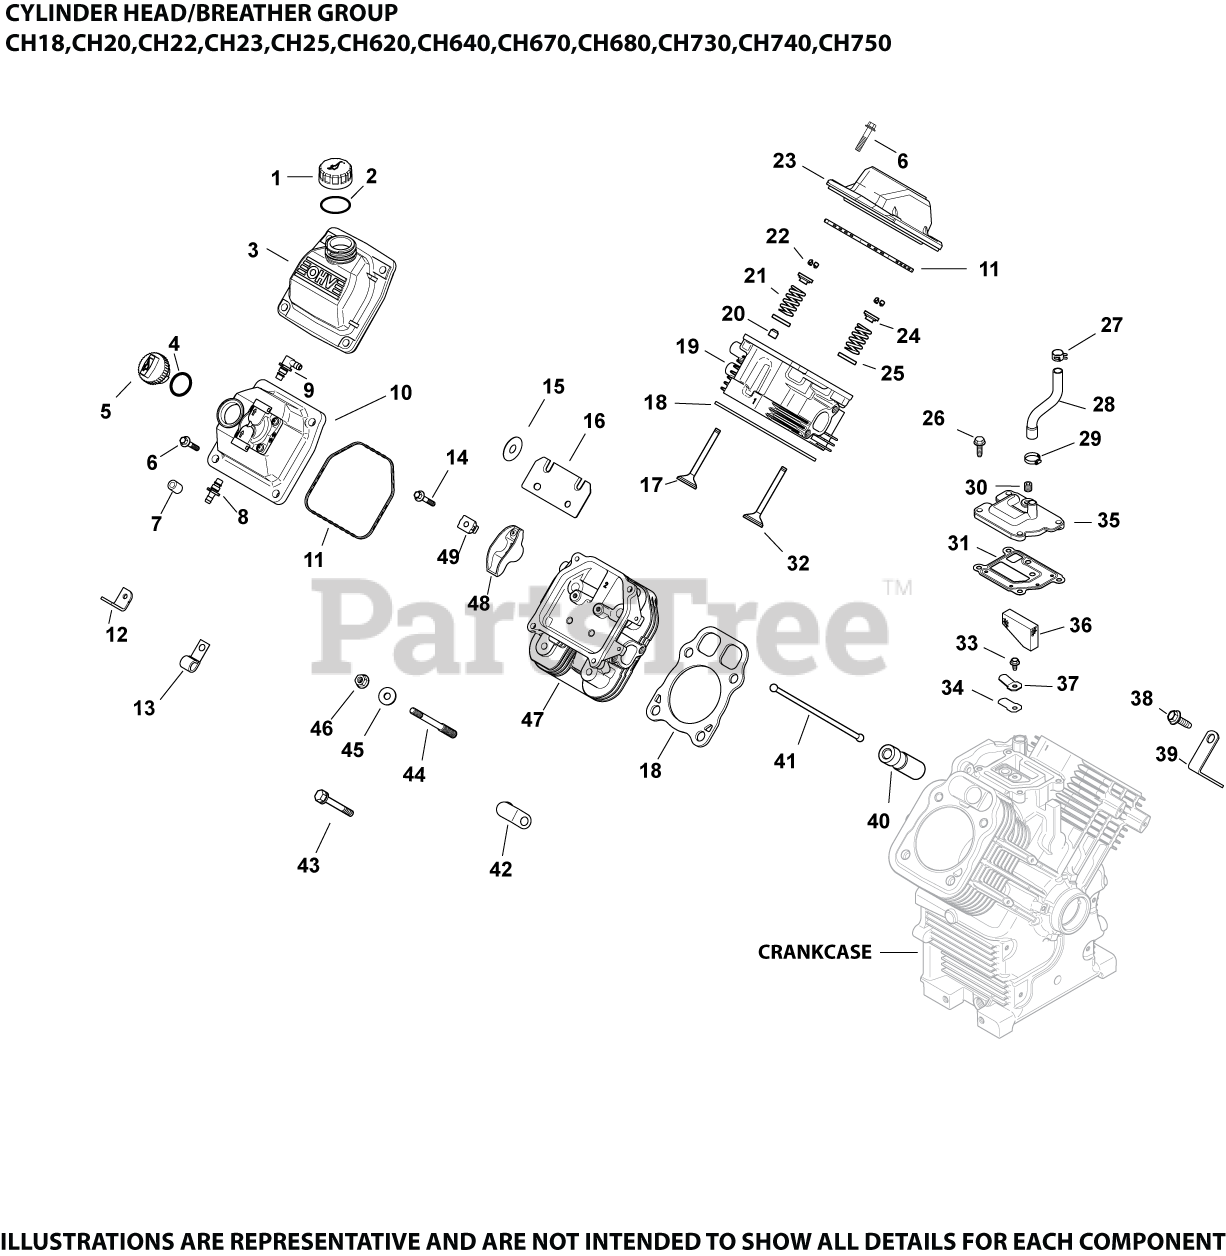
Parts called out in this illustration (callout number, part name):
1	KIT, OIL FILL CAP (YELLOW)
2	O-RING, DIPSTICK
3	KIT, VALVE COVER-OIL FILL
6	SCREW, FLG M6X1.0X30
11	O-RING (YELLOW), VALVE COVER
12	STRAP, LIFTING
14	SCREW, FLG M6X1.0X34
17	VALVE, EXHAUST (STD) - USE 32 016 01-S
17	VALVE, EXHAUST (.25)
18	KIT, CYL HEAD GASKET (C17-22)
19	KIT, #1 CYL HEAD ASSY-(#24318144S)
20	SEAL, VALVE STEM - (#2503214S)
21	SPRING, VALVE
22	KIT, RETAINER
23	KIT, VALVE COVER-PLAIN
24	CAP, VALVE SPRING
25	RETAINER, SPRING
26	SCREW,FLG THD FRM M6X1.0X20-(#25086396S)
27	CLAMP, BAND SPRING HOSE-(#2523737S)
28	HOSE, BREATHER
31	GASKET, BREATHER
32	VALVE, INTAKE (STD)
32	VALVE, INTAKE (.25)
33	SCREW, FLG THD FRM M5X.8X10
34	REED, BREATHER
35	KIT, BREATHER ASSEMBLY
36	FILTER, BREATHER
37	RETAINER, REED
38	SCREW,FLG THD FRM M6X1.0X25-(#25086395S)
39	STRAP, LIFTING-USE 25 445 03-S
40	LIFTER, VALVE HYDRAULIC-USE 25 351 10-S
41	ROD, PUSH
43	SCREW, FLG M10X1.5X90
47	KIT, #2 CYL HEAD ASSY - (#24318150S)
48	ARM, ROCKER
